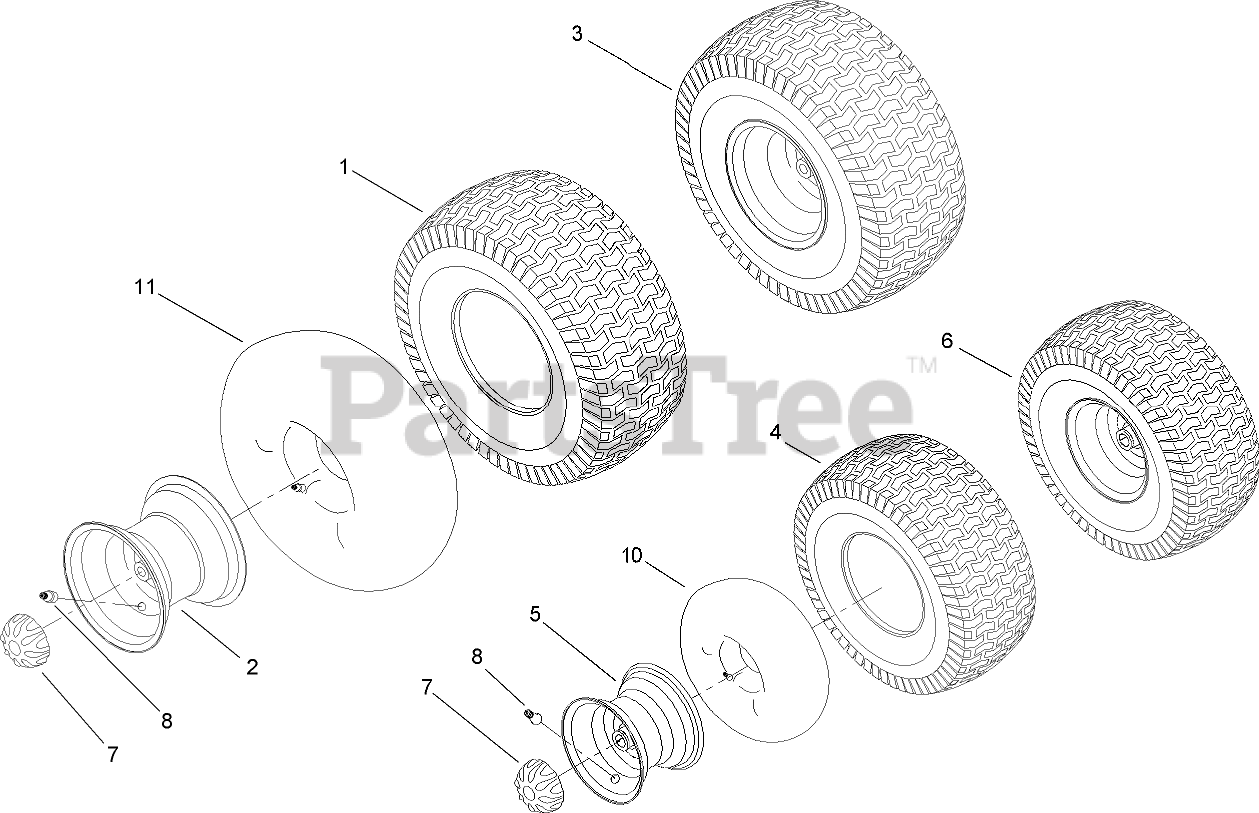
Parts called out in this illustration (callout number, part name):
1	TIRE-MULTI TRAC
2	RIM-WHEEL, Rear
3	Rear WHEEL ASM
4	TIRE-FRONT
5	Rim-Wheel, Front
6	Front WHEEL ASM
7	CAP-HUB
8	VALVE-AIR, TUBELESS
10	TUBE-INNER
11	TUBE-INNER
